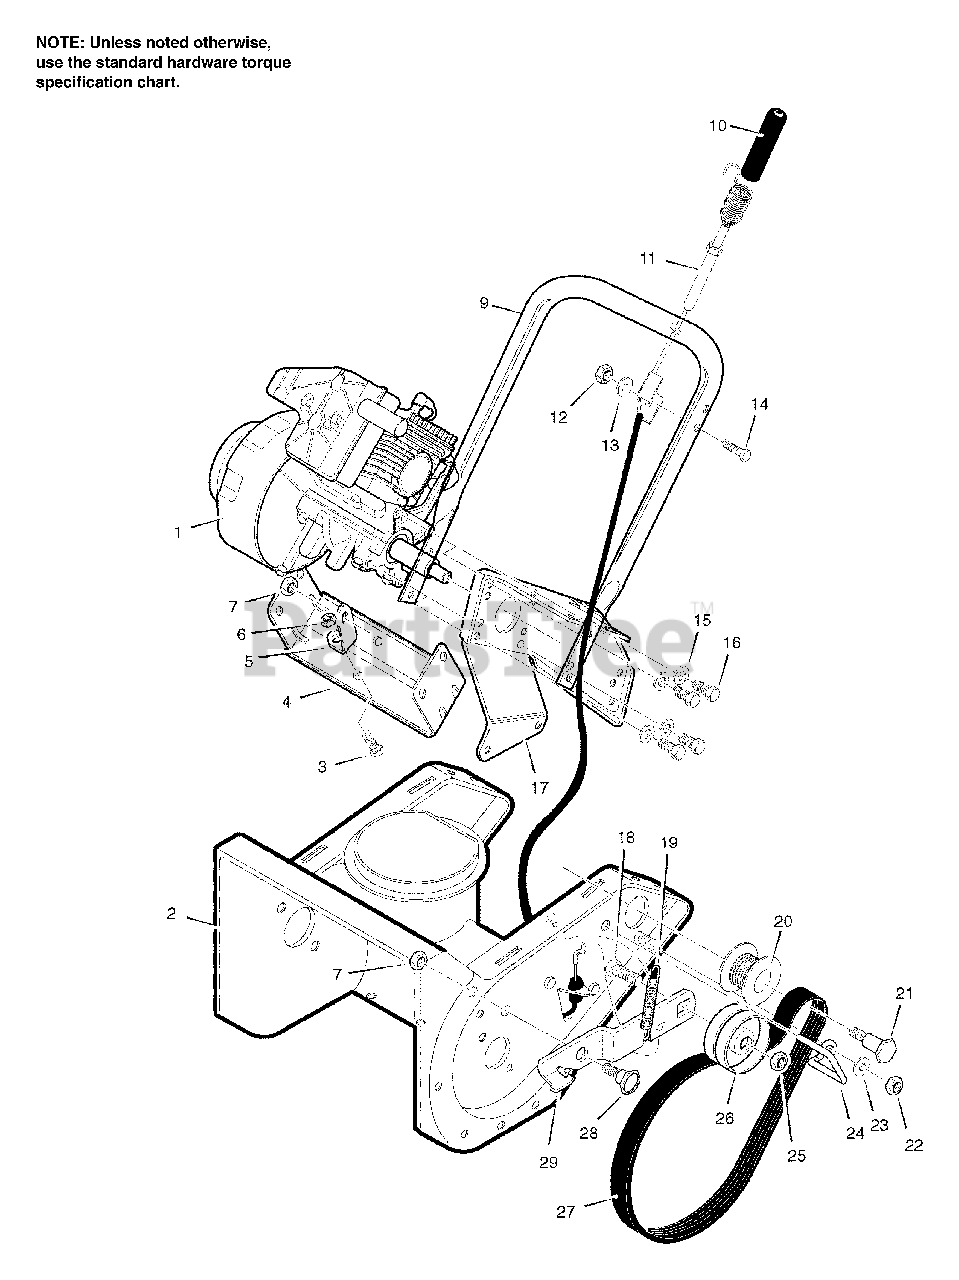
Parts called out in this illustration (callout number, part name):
1	ENGINE
2	AUGER HOUSING, 21"
3	SCREW, .31-18 x .5
4	SUPPORT, FRAME
5	SUPPORT, ENGINE
6	NUT.31-18 HEX
7	NUT .31-18 HEX
9	HANDLE, LOWER
10	COVER, CABLE SPRING
11	CABLE, DRIVE
12	LOCKNUT .25-20 HEX
13	WASHER .286-0.62-.07
14	SCREW .25-20 x 1.50
15	WASHER .318-0.56-.05
16	SCREW, .31-18 x .63
17	PLATE, REAR
18	BOLT, CARRIAGE .38-16 x 1.50
19	SPRING, IDLER BRAKE
20	PULLEY, 4.5 HP
21	BOLT, SHOULDER .625 x .280
22	NUT.31-18 HEX
23	WASHER, FLAT .312 x .73 x .065
24	GUIDE, BELT
25	JAM NUT.38-16 HEX
26	PULLEY, IDLER
27	BELT, POLY-V 10 RIB 35.14
28	BOLT, SHOULDER
29	BRACKET, IDLER ARM
